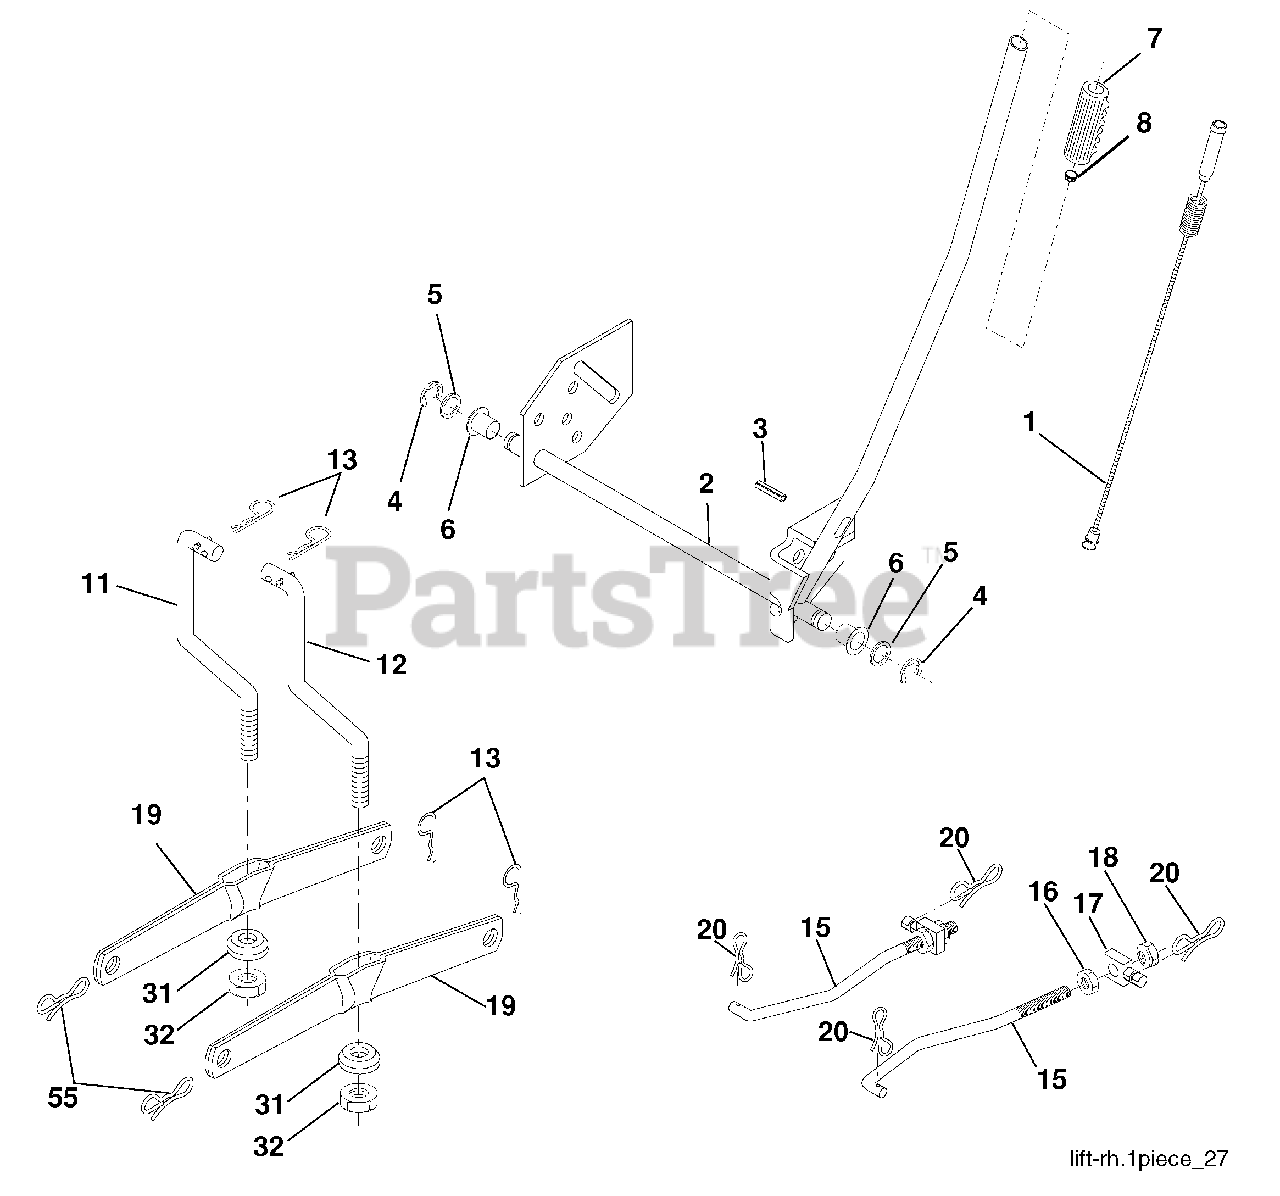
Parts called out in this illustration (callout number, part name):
1	Wire Asm Inner/Sprg w/plunger
2	Shaft Asm Lift RH
3	Pin Groove 1 500 Zinc
4	E Ring #5133-62
5	Washer 21/32 x 1 x 21 Ga.
6	Bearing Nylon Blk 629 Id
7	Grip Handle Bicycle Matte Blk
8	Button Plunger Black
11	Link Lift LH Fixed Length
12	Link Lift RH Fixed Length
13	Retainer Spring
15	Link Front
16	Nut Jam Hex 1/2-13 unc
17	Trunnion
18	Nut Lockw/Wsh 1/2-13 unc
19	Arm Suspension Rear
20	Pin Cotter 7/16 Bow Tie Lock
31	Bearing Pvt Lift
32	Nut Crownlock 3/8-24
55	Pin Cotter 5/16 Bow Tie Lock
